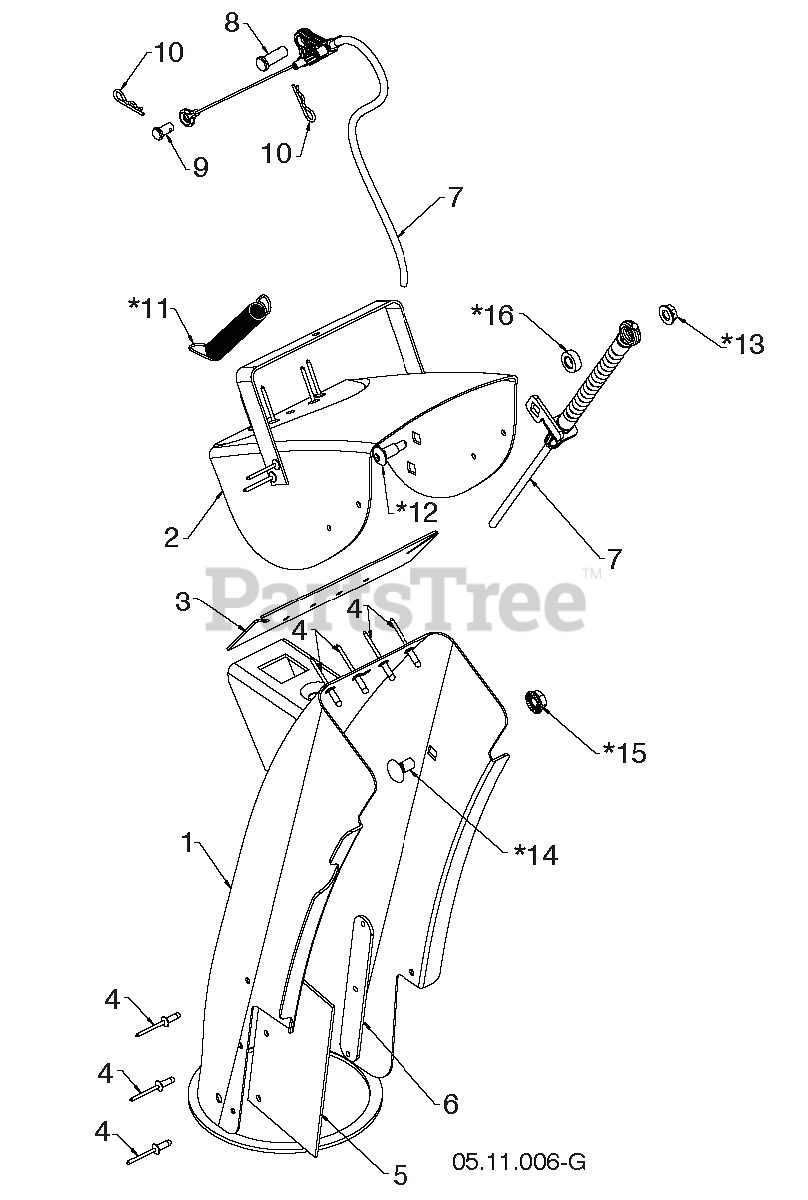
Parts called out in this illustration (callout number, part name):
1	ASM.CHUTE/DEFLECTOR.668
7	CABLE.CONTROL.CHUTE.DEFLEC
8	PIN CLEVIS 5/16X.875
9	PIN CLEVIS .25 X .31
10	HAIRPIN.SOFT.ZINC.059X1.125
